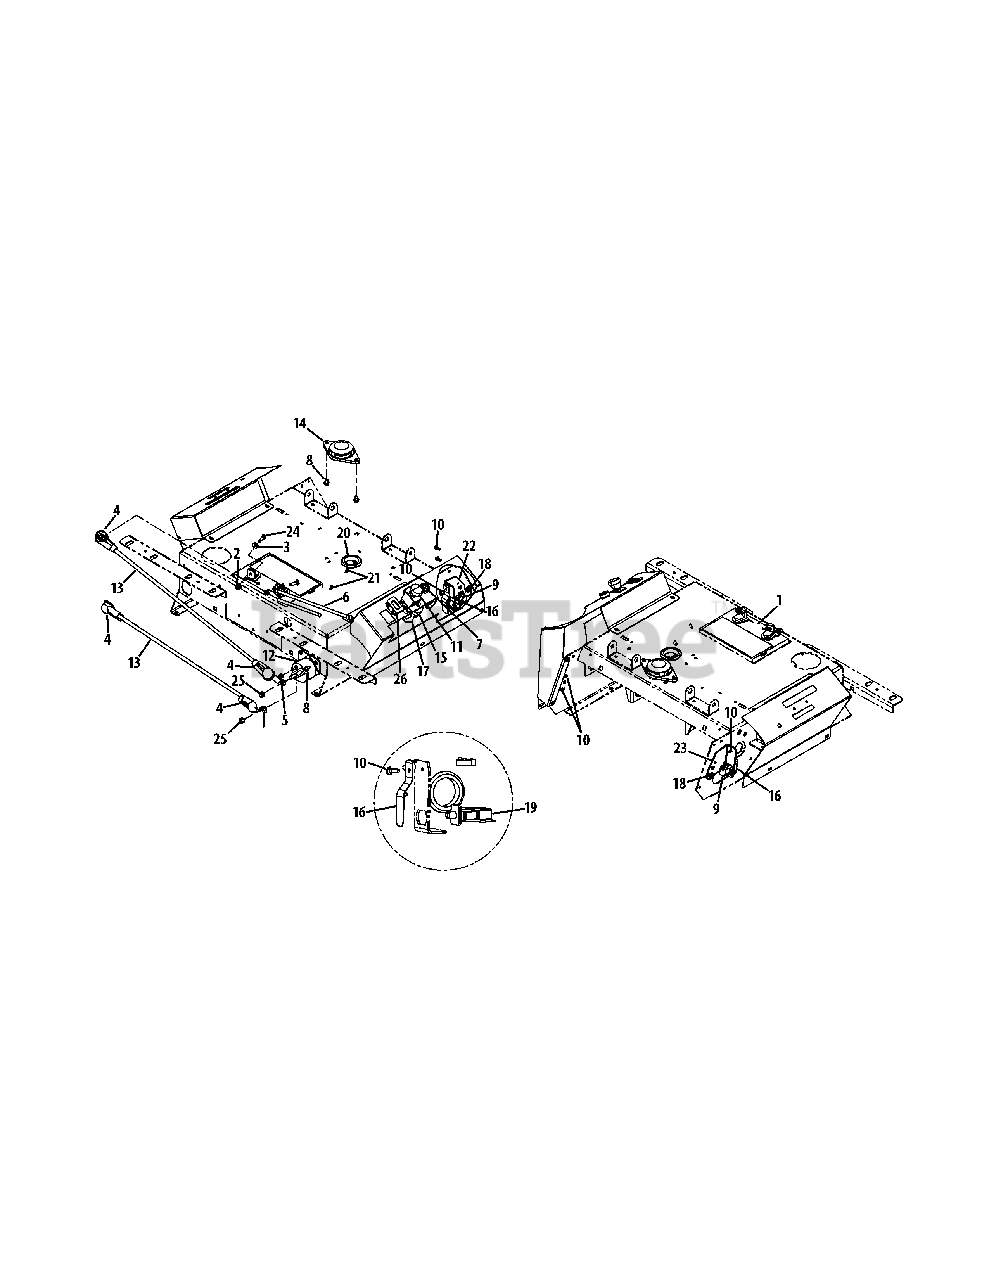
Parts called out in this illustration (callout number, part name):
2	Nylock Nut, 1/4-20
3	Washer, .281 x .625 x .063
4	Boot Terminal, 1.00 x 2.50
5	Nylock Nut, #10-32
6	Battery Cable
7	Nut, 5/8-32
8	Hex Flange Screw, 1/4-20 x .500
9	Switch
10	Flange Screw, #10-24 x .500
11	PTO Switch
12	Solenoid
13	Battery Cable
14	Seat Switch
15	Ignition Switch
16	Renovator Spring
17	PTO Bracket
18	Nut, #10-24
19	Delta Switch
20	Grommet, 1/8 x 1.5 x 2.13
21	Electric CDT Clip
22	RH Deck Switch Mount Bracket
23	LH Deck Switch Mount Bracket
24	Hex Screw, 1/4-20 x .75
25	Hex Lock Nut, 5/16-18
26	Hour Meter
NS	Wiring Harness
NS	Harness Assembly
